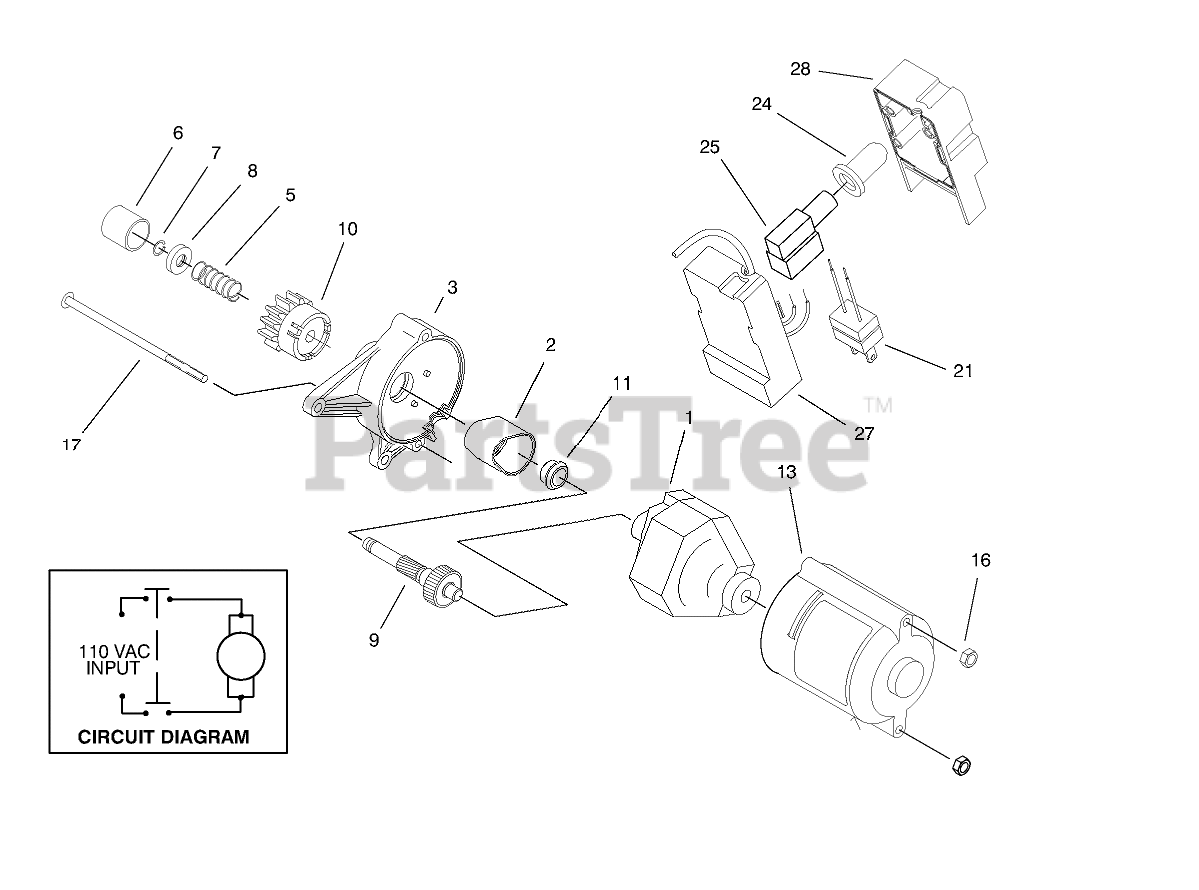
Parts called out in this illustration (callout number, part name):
1	STARTER MOTOR ASM
2	COVER-GEAR
3	Housing-Starter
5	SPRING
6	CAP-PINION
7	RING-LOCK
8	PINION STOP
9	Asm-shaft & Gear
10	PINION ASM
11	BUSHING
13	HOUSING COVER
16	NUT-LOCK, NI
21	PLUG-POWER
24	BOOT-SWITCH
25	SWITCH-STARTER
27	OBS BASE X
28	Cap-Switch Housing
